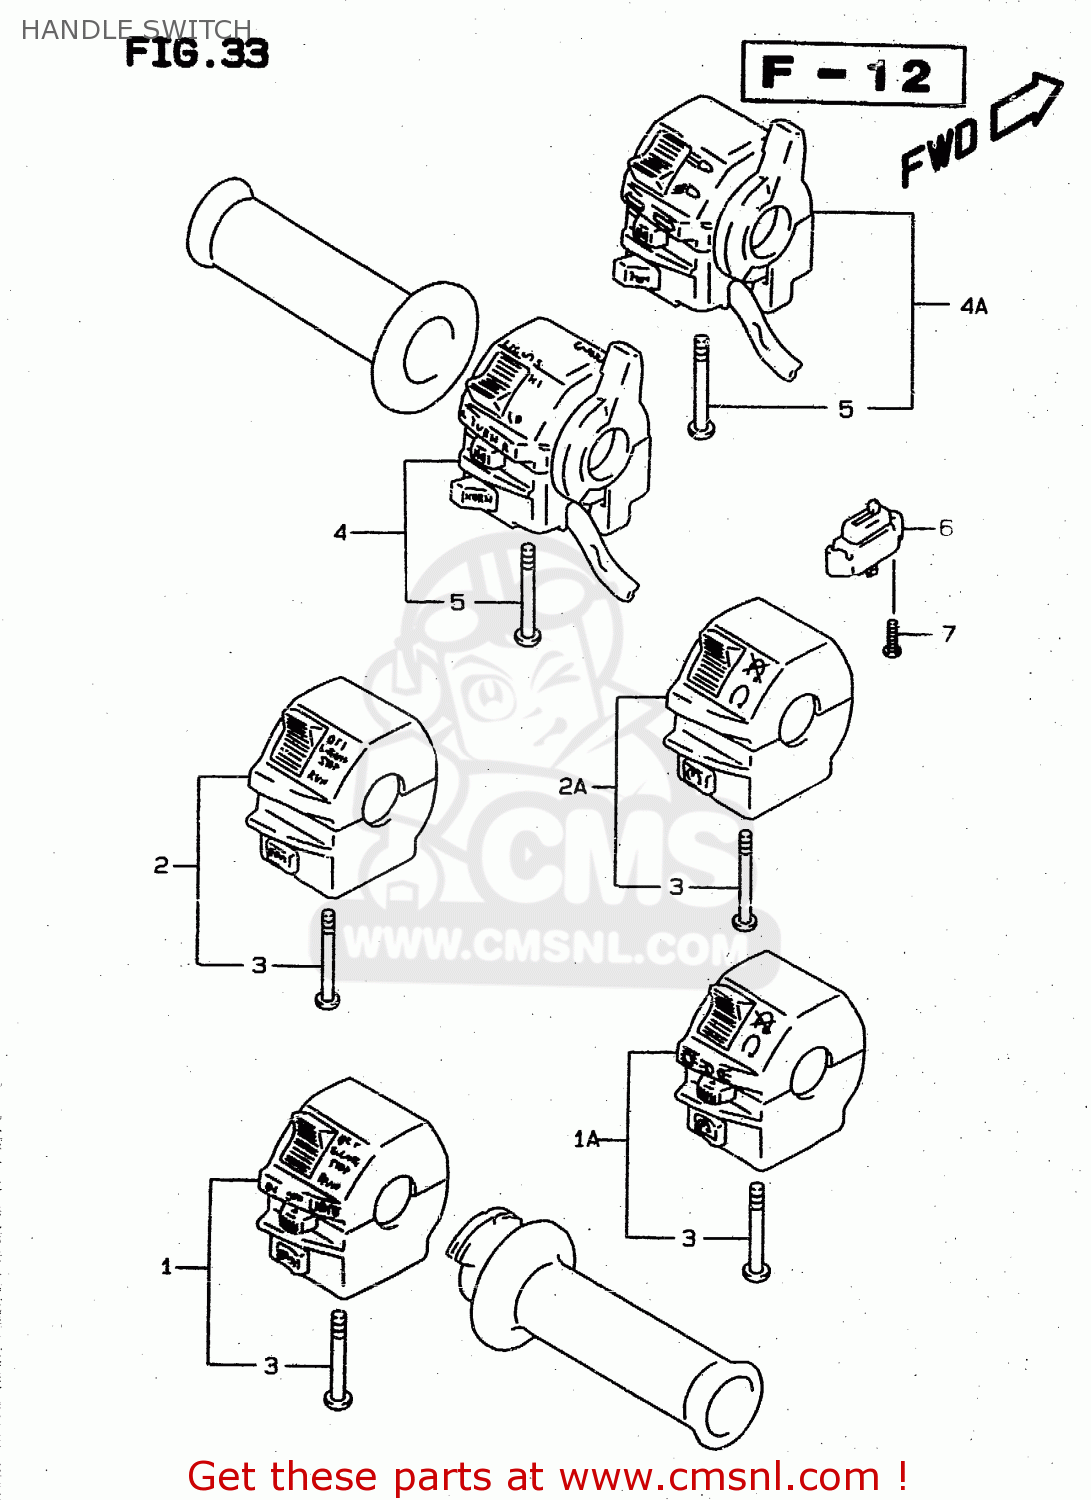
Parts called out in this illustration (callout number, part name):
1	SWITCH,HANDLE,
1A	SWITCH ASSY,HANDLE,R
2	SWITCH ASSEMBLY,HANDLE,RIGHT
2A	SWITCH ASSY,HANDLE,R
3	SCREW, 5X45
4	SWITCH,HANDLE,
4A	SWITCH ASSY,HANDLE,L
5	SCREW, 5X45
6	SWITCH ASSY,CLUTCH
7	SCREW
